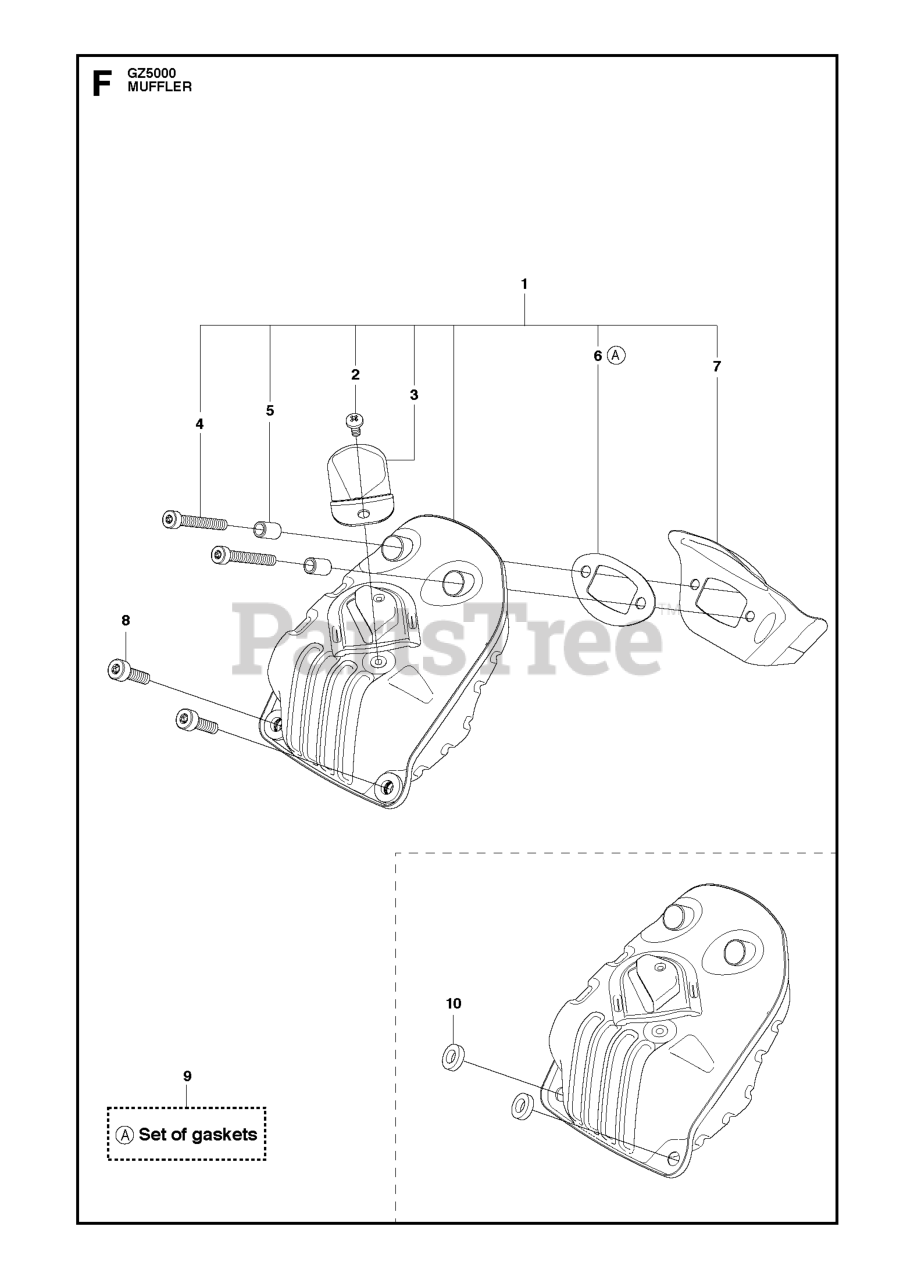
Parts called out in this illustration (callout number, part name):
1	MUFFLER KIT
2	SCREW CRPANM
3	SPARK ARRESTER A004 50 CC
4	SCREW ITXSCM M6X35 T27 12.9 T
6	GASKET MUFFLER
7	HEAT DEFLECTOR
8	SCREW ITXSCM M6X20 T27 10.9 Z
9	GASKET KIT 50CC
10	WASHER
